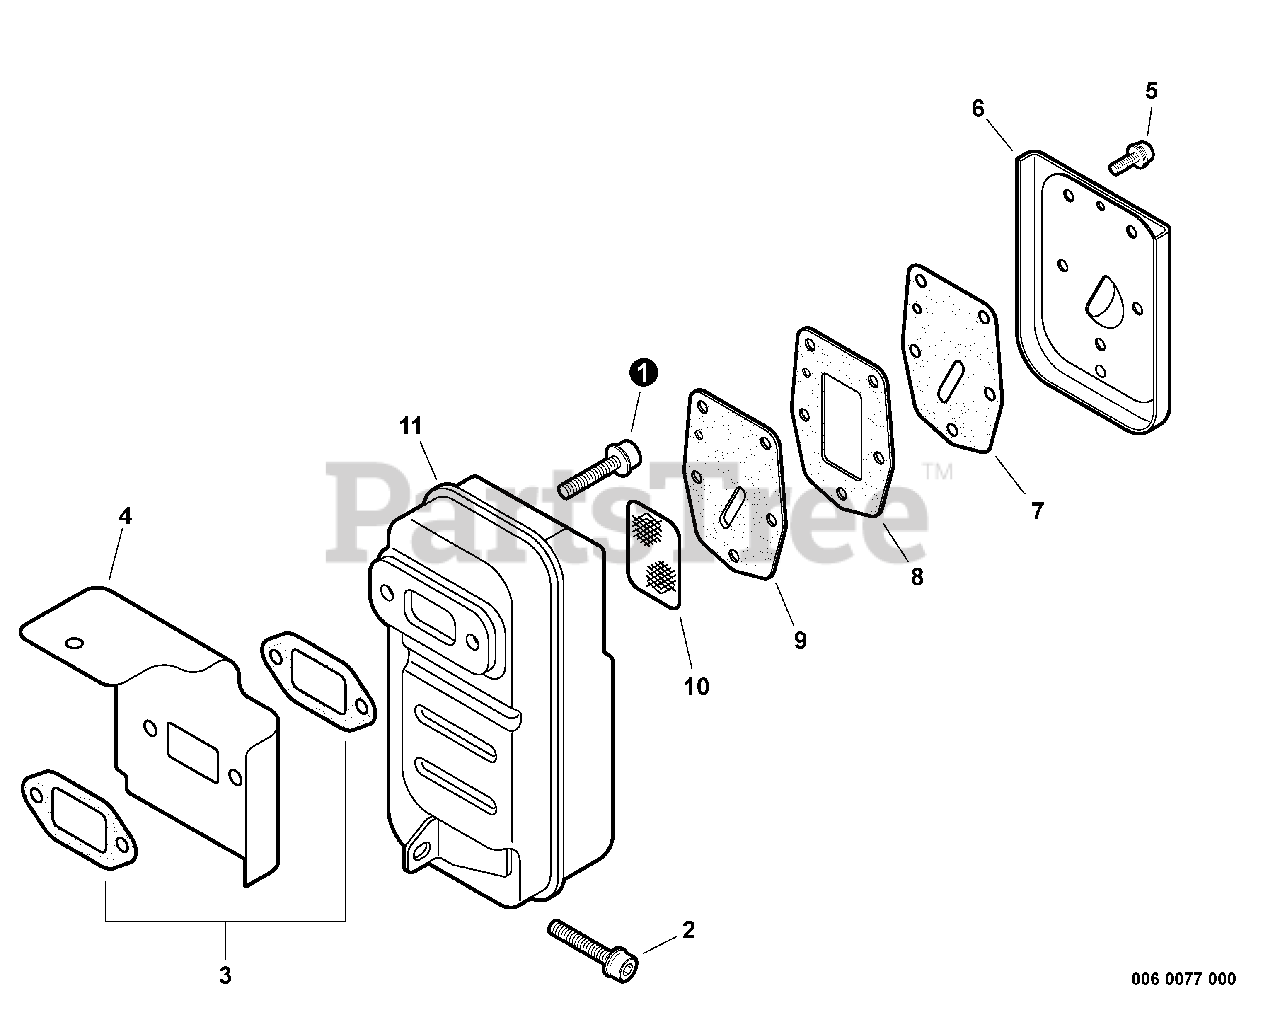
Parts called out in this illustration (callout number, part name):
1	SCREW - 6X20
2	SCREW - 5X20
3	GASKET, EXHAUST
4	SHIELD, CYLINDER - EXHAUST
5	SCREW - 4X14
6	GUIDE, EXHAUST
7	GASKET, EXHAUST
8	GASKET, EXHAUST
9	GASKET, EXHAUST
10	SCREEN, SPARK ARRESTOR
11	MUFFLER
